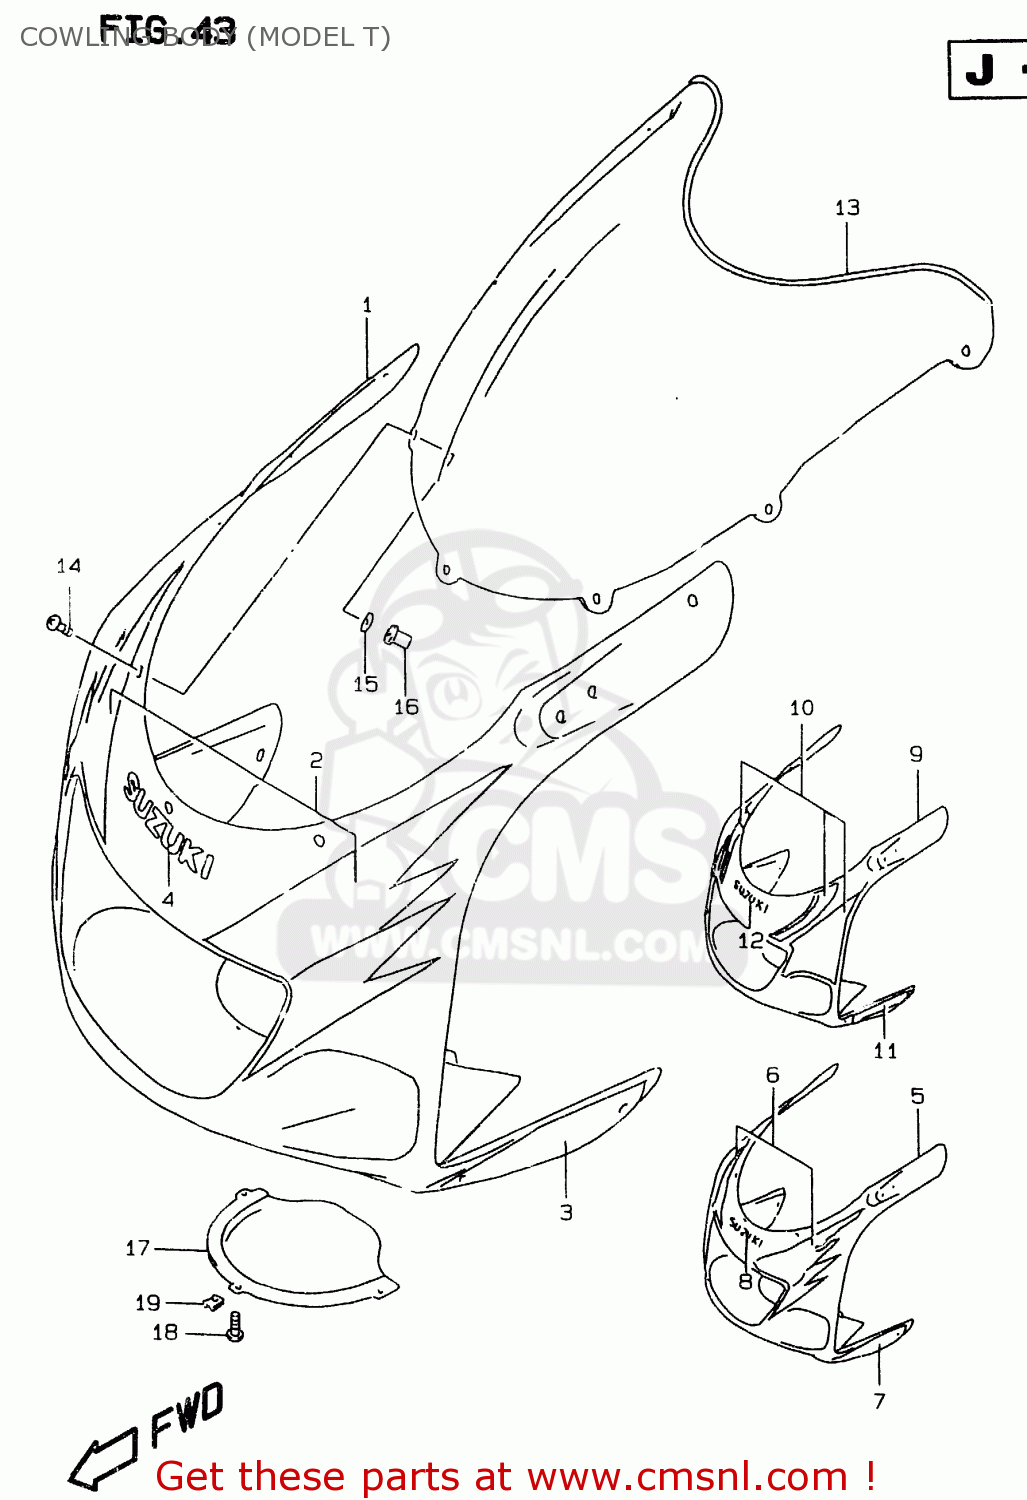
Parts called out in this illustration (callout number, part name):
1	COWLING ASSY,BODY
2	TAPE,COWL BODY FR
3	TAPE,COWL BODY SIDE
4	EMBLEM,COWLING UPR
5	COWLING ASSEMBLY,BODY
6	TAPE SET,COWL BODY FR
7	TAPE,COWL BODY SIDE
8	EMBLEM,COWLING UPR
9	COWLING ASSY,BODY
10	TAPE SET,COWLING BODY
11	TAPE,COWL BODY SIDE
12	EMBLEM,SUZUKI
13	WINDSCREEN
14	SCREW(5X14)
15	WASHER
16	NUT
17	LID,BODY COWLING,LOWER
18	SCREW
19	NUT
